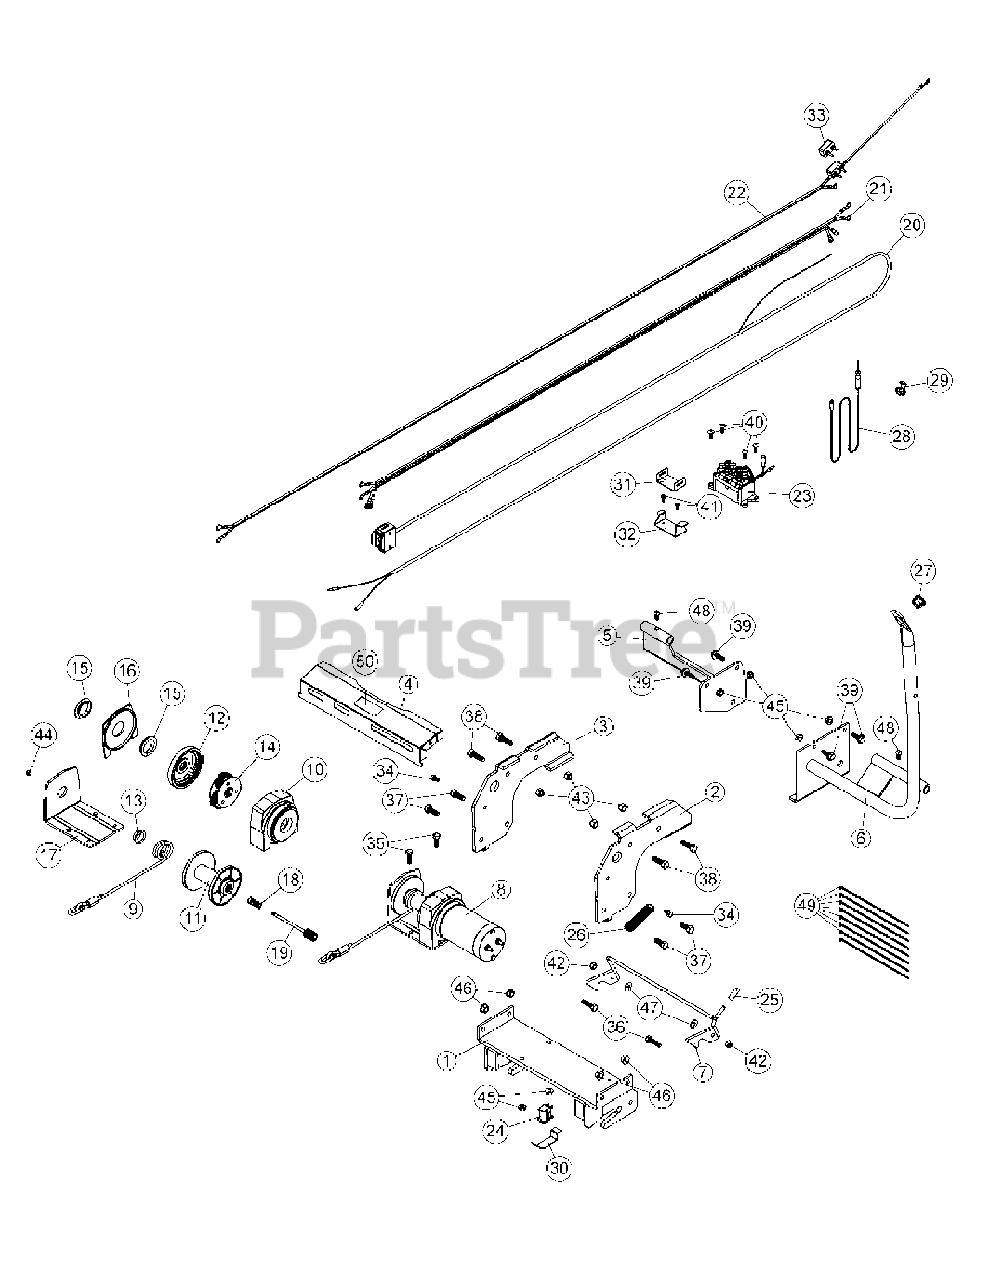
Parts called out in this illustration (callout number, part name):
1	Female hitch
2	Left support
3	Right support
4	Heat shield
5	Cab support
6	Handle support
8	Winch assembly
9	Winch cable
10	Reduction box
12	Inner gear
14	Planetary gear
15	Drum support bushing
16	Drum support plate
17	Base plate assembly
19	Spline shaft
20	Winch control
21	Wire assembly
22	Wire assembly
24	Limit switch
27	Plastic grommet
28	Hi/low voltage tester
29	Instant connector
30	Push plate
31	Control base
32	Control support
34	Hex. bolt 1/4" n.c. x 1/2"
35	Hex. bolt 5/16" n.c. x 1"
36	Hex. bolt 5/16" n.c. x 1 1/4"
37	Hex. bolt 3/8" n.c. x 1"
38	Hex. bolt 3/8" n.c. x 1 1/4"
39	Thread cutting screws 5/16" n.c. x 1"
40	Metal screw T.H. #12 x 3/4"
41	Metal screw pan head #8 x 1/2"
42	Nylon insert lock nut 5/16" n.c.
43	Nylon insert lock nut 3/8" n.c.
44	Nylon insert lock nut M6 x 1.00
45	Flange nut 5/16" n.c.
46	Flange nut 3/8" n.c.
47	Flat washer 5/16" hole
48	Square head set screw 5/16" n.c. x 1/2"
49	Tie wrap 8"
50	Decal caution hot surfaces
